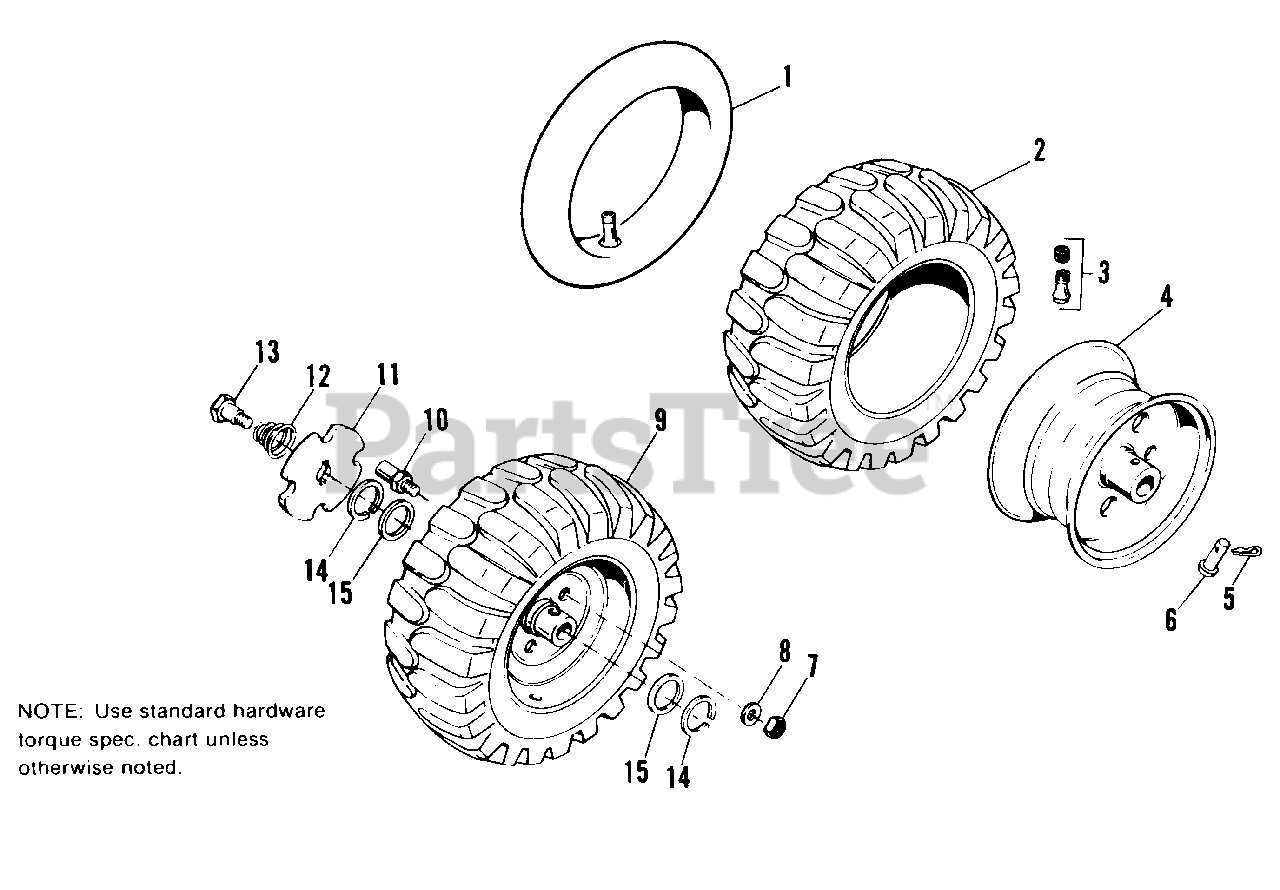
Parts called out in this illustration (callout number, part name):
1	TUBE (Field Repair)
3	VALVE STEM & CAP
4	WHEEL & HUB ASSY.
5	PIN, Quick
6	PlN
7	LOCKNUT, Hex, 3/8-16
8	WASHER, Plain, 5/16
9	WHEEL & TIRE ASSY.
13	BOLT, Shoulder
14	RING, Retaining
15	WASHER, Special
